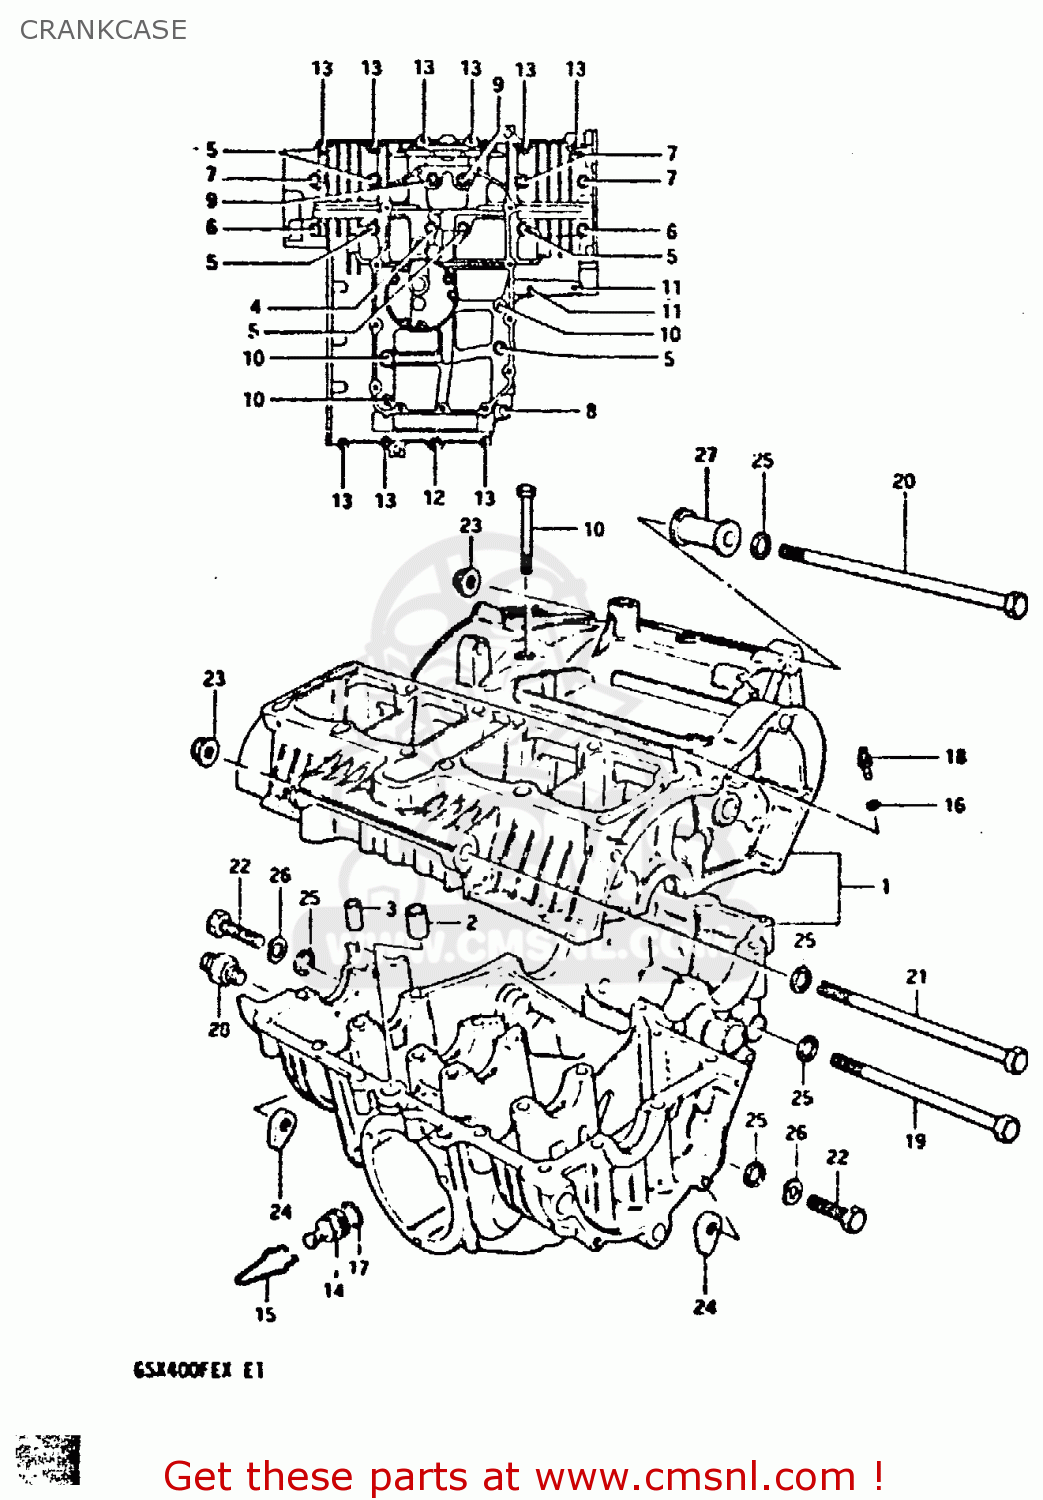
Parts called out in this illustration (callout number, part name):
1	CRANKCASE SET
2	PIN(10.4X13X22)
3	PIN (11X20)(SUS)
4	BOLT
5	BOLT
6	BOLT
7	BOLT
8	BOLT
9	BOLT
10	BOLT
11	BOLT (6X75)
12	BOLT
14	BOLT
15	CLIP
16	O-RING,OIL GALLERY JET
17	O RING(D:1.9,ID:11)
18	JET,AIR(14)
19	BOLT 10X160
20	BOLT 10X230
21	BOLT (10*180)
22	BOLT,M10X1.25X
23	NUT 10MM
24	NUT
25	WASHER
26	LOCK WASHER
27	SPACER,ENGINE MOUNT
28	SWITCH ASSEMBLY
